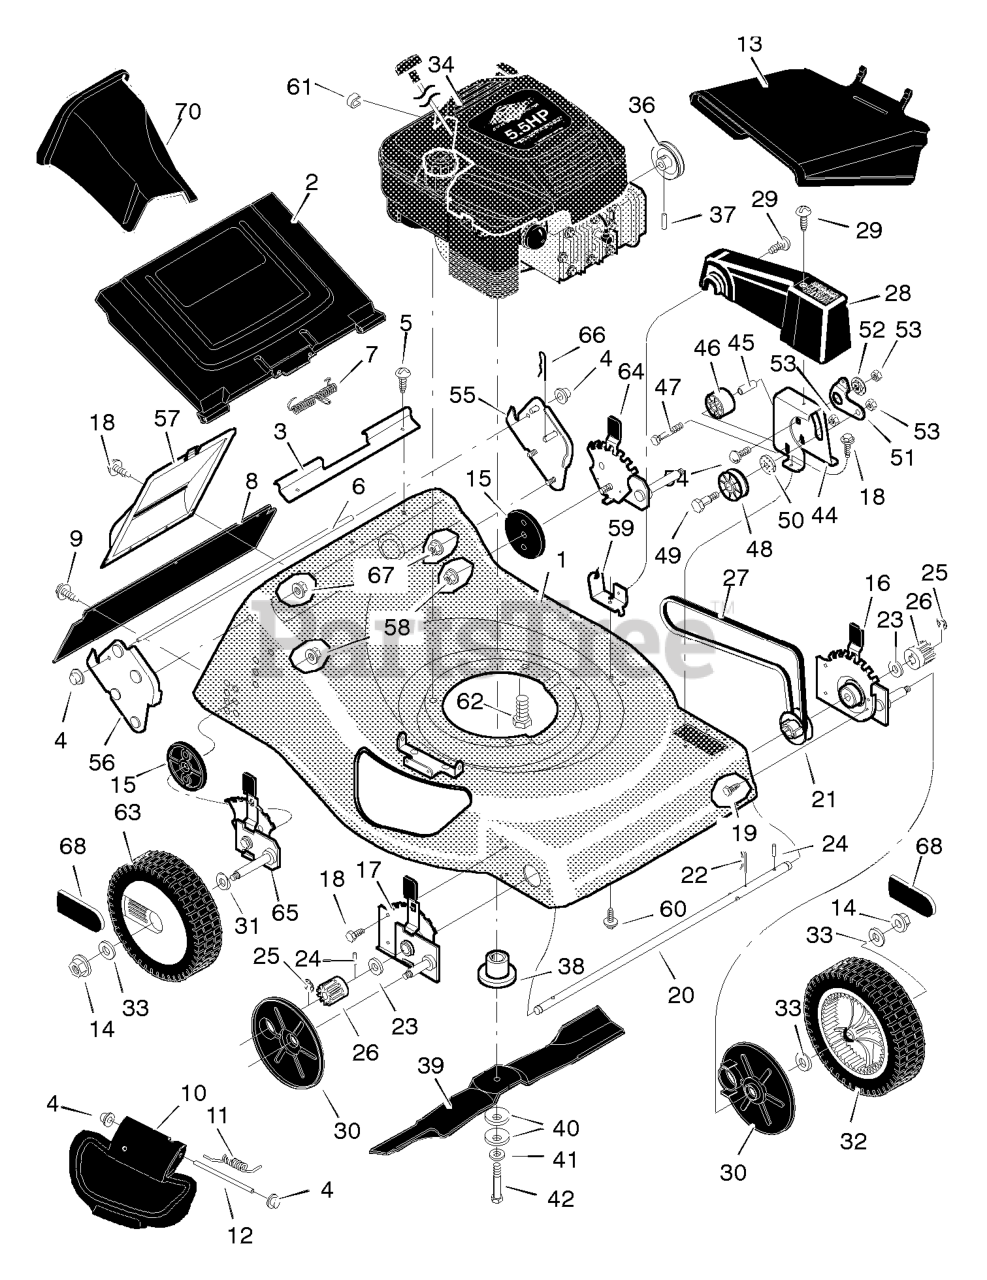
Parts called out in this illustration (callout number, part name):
1	Housing
2	Door, Rear
3	Spacer, Door
4	Push On Cap
6	Rod, Door Pivot
7	Spring, Torsion
8	Guard, Rear
10	Cover, Mulcher
11	Spring, Torsion
13	Deflector, Chute
14	Locknut, Flange
16	Height Adjuster, Left Front
17	Height Adjuster, Right Front
22	Hair Pin
24	Pin, Drive
25	Ring, Retainer
26	Gear, Pinion
27	Belt, Briggs Engine
28	Cover, Belt
30	Cover, Dust
32	Wheel, Drive
33	Washer
34	Engine *
36	Pulley, Engine
37	Pin, Spring
38	Adapter, Blade
40	Washer, Belleville
44	Bracket, Idler
45	Bearing
46	Pulley, Idler
48	Pulley, Idler
49	Bolt, Shoulder
51	Arm, Idler
53	Locknut
54	Bolt, Carriage
55	Handle Bracket, Left
56	Handle Bracket, Right
57	Cover, Transmission
58	Nut, Flange
59	Cable Bracket
61	Stop, Rope
62	Bolt, Engine Mount
63	WHEEL & TIRE ASSEMBLY, White, 8"
64	Height Adjuster, Rear
66	Pin, Hair
67	Nut, Hex
68	Hub Cap
70	Plug, Mulcher
